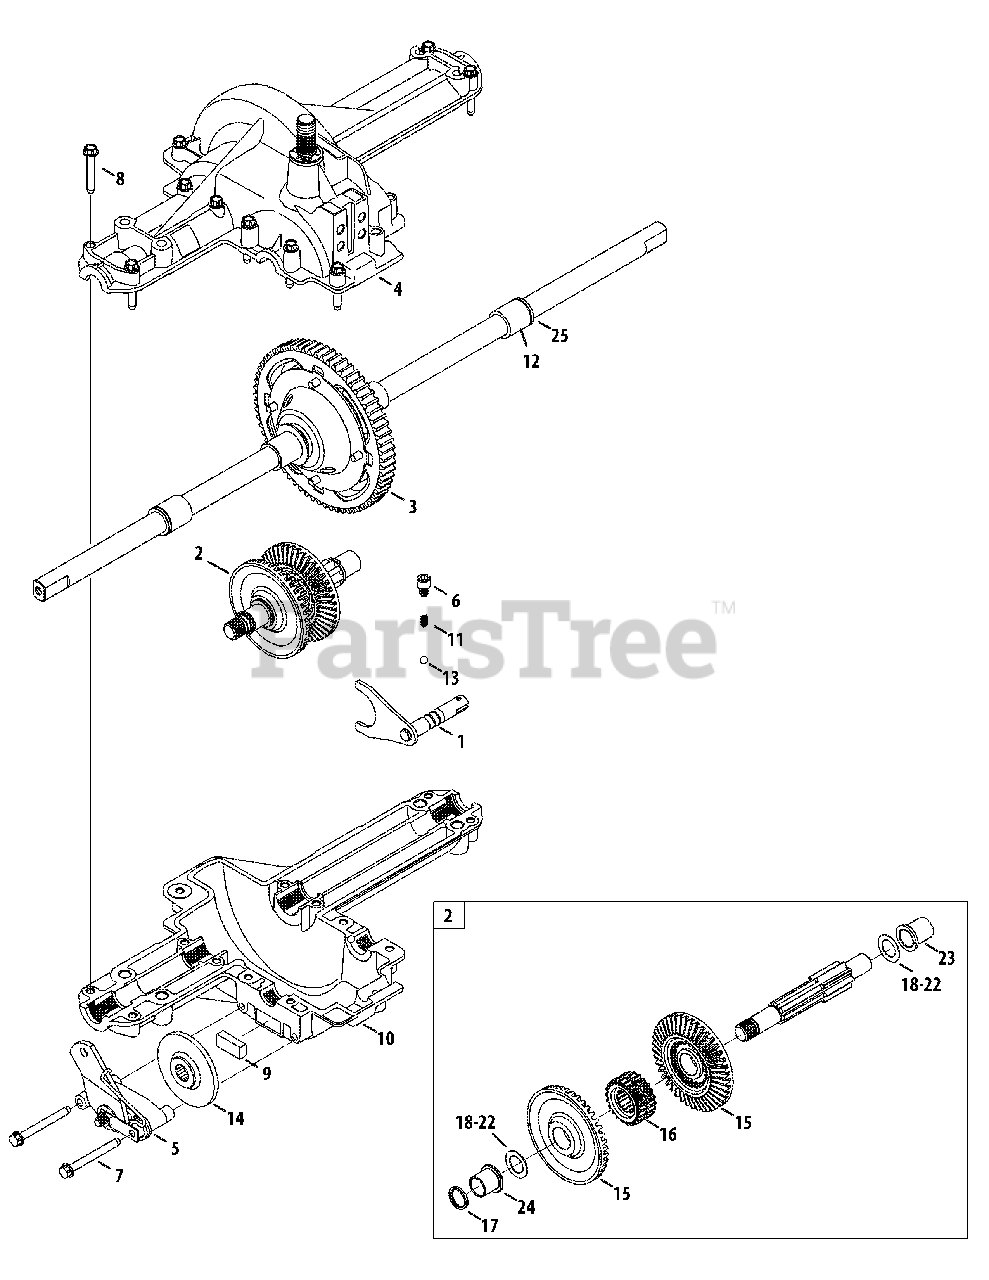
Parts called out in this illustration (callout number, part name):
1	Shaft Ass’y, Detent
2	Shaft Ass’y, Drive, Fwd-Rev
3	Differential Ass’y
4	Housing Ass’y, Upper
5	Brake Ass’y, Yoke, RH
6	Shcs, Self-tapping, 5/16-18, .375
7	Screw, Self-tapping, 1/4-20, 2.375,
8	Screw, Self-tapping, 1/4-20, 1.625,
9	Pad, Brake
10	Housing, Lower
11	Compression Spring
12	Bearing, Sleeve, .75 x 1.00 x .42
13	Ball, Detent, .250
14	Disc, Brake
15	Gear, Bevel, 42t, Spline
16	Collar, Clutch
17	Seal, .625 x .812 x .094
18	Washer, Flat, 5/8x1.00x.030 Hd
19	Washer, Flat, .634x1.00x.04,
20	Washer, Flat, .63 x 1.00 x .02
21	Washer, Flat, .632x1.00x.035
22	Washer, Thrust, 1.00 x .632 x .0
23	Bearing, Flange, 5/8 x 3/4 x 3/4
24	Bearing, Flange, 5/8 x 3/4 x 15/16
25	Seal, .75 x 1.00 x .125
